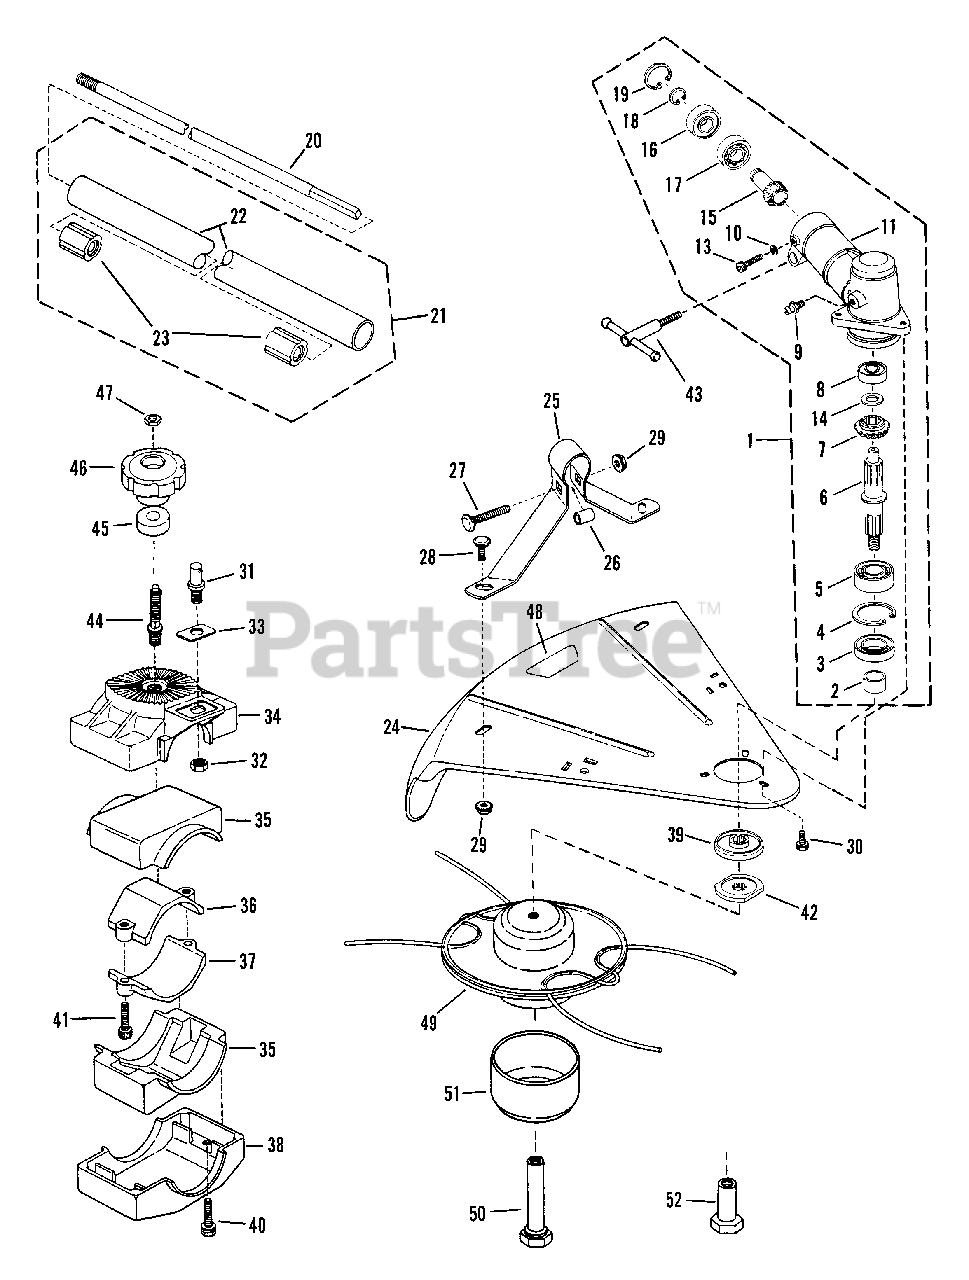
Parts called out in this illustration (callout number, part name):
1	ASSEMBLY, Gear Head
2	SLEEVE, Spline
3	SEAL, Oil
4	RING, Snap 35mm
5	BEARING
6	SHAFT, Spline
7	GEAR, Bevel
8	BEARING
9	FITTING, Lube
11	CASE, Gear
12	BOLT, M6 x 20mm Socket
13	BOLT, M5 x 15mm Socket
14	WASHER, Thrust
15	PINION, Bevel
16	BEARING
17	BEARING
18	RING, Snap
19	RING, Snap 26mm
20	SHAFT, 5/16 Drive
21	ASSEMBLY, Tube & Bushing
22	TUBE, Main
23	BUSHING
24	SHIELD, Steel
25	BRACE, Shield
26	SPACER, 7/16 x 1"
27	BOLT, 5/16-18 x 1-1/2 Short Neck Carriage
28	BOLT, 5/16-18 x 1/2 Short Neck Carriage
29	NUT, 5/16-18 Hex Flange Lock
30	SCREW, M5 x 10mm Hex
31	PIN, Guide
32	NUT,3/8-24 Hex Flange Lock
33	PLATE, Mounting Pin
34	JOINT "D", Handle
35	RUBBER, Vibro
36	CLAMP "A", Tube
37	CLAMP "B", Tube
38	JOINT "C", Handle
39	HOLDER "A"
40	SCREW, M6 x 30mm, Cross Hex Head
41	SCREW, M6 x 10mm, Socket Hex Head
42	HOLDER "B"
43	T-BOLT, M6
44	BOLT, Latch
45	SPACER, Knob
46	KNOB, Torque
47	NUT, Self-Threader
48	LABEL, Direction
49	HEAD, Fixed Line
50	BOLT, Arbor
51	BALL, Glide
52	ARBOR, Bolt/Blade
53	NUT, M10 x 1.25 Hex Lock (Left Thread)
